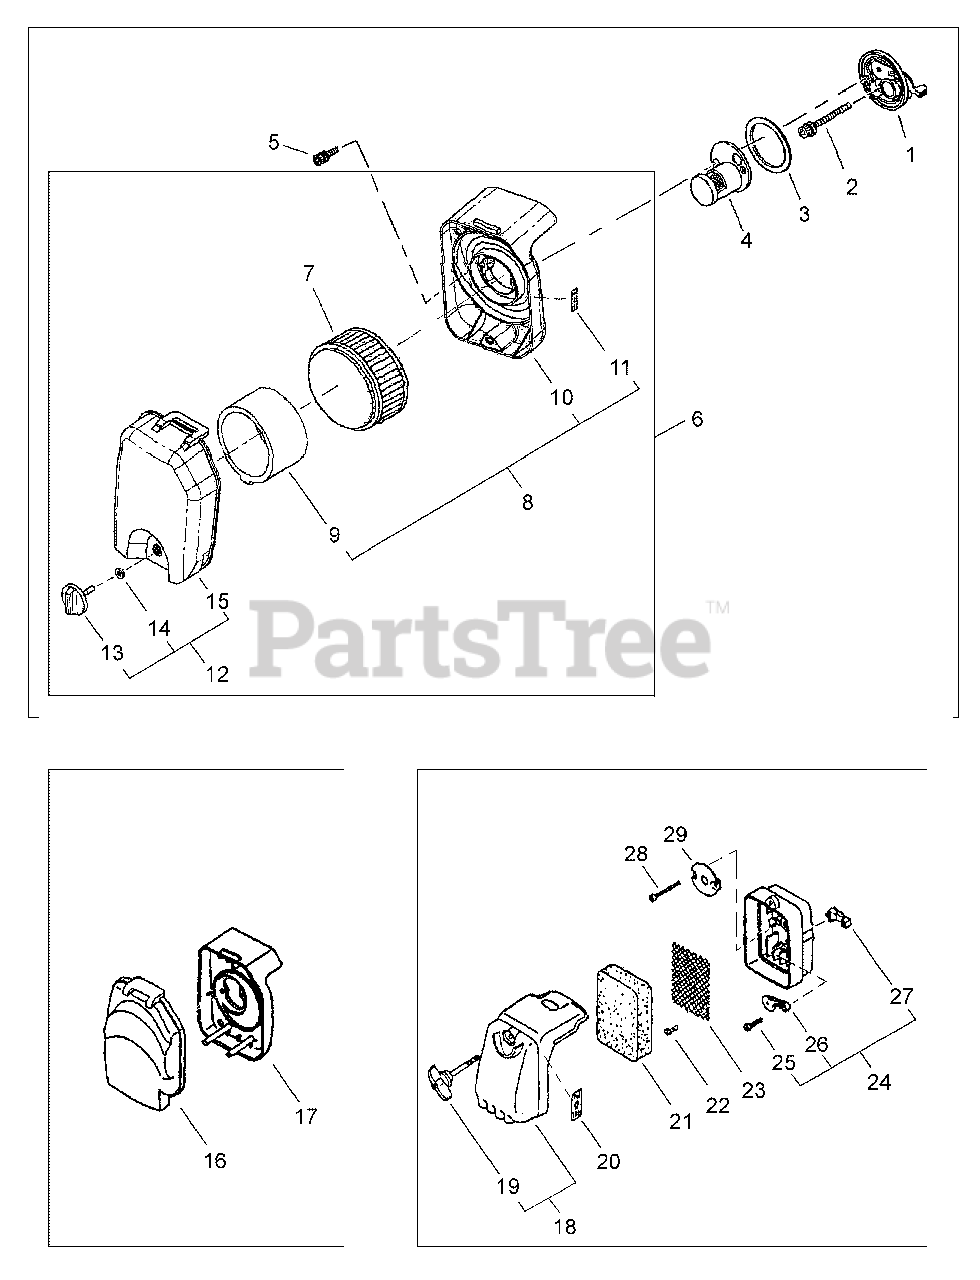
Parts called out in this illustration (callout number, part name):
1	CHOKE ASSY
2	BOLT M5×50
3	GASKET, INTAKE
4	PIPE, INTAKE
5	BOLT M4×14
6	FILTER ASSY, AIR
7	FILTER, AIR
8	FILTER KIT, AIR
9	PRE-FILTER, FOAM
10	CASE, AIR FILTER
11	LABEL, CHOKE
12	COVER ASSY, AIR FILTER
13	THUMBSCREW
14	WASHER 5
15	COVER, AIR FILTER
16	COVER, AIR FILTER
17	CASE, AIR FILTER
18	COVER ASSY, AIR FILTER
19	THUMBSCREW
20	LABEL, CHOKE
21	FILTER, AIR
22	SCREW
23	SCREEN, FILTER
24	CASE ASSY, AIR FILTER
25	SCREW
26	PLATE, SHUTTER
27	LEVER, CHOKE
28	SCREW
29	PLATE, PREVENT
